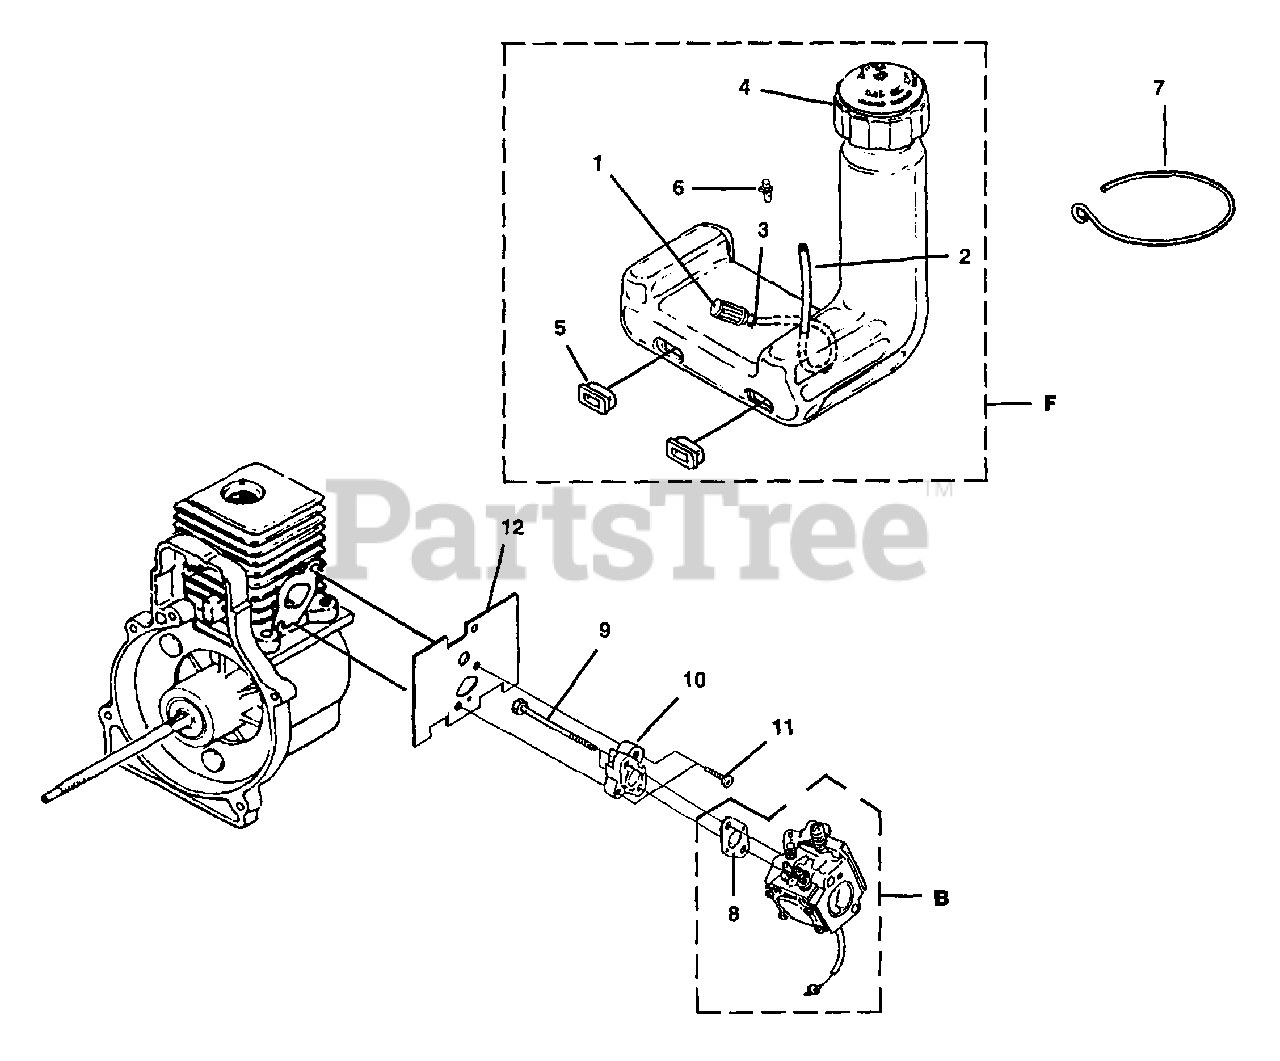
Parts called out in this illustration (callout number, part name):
1	FILTER-Fuel
2	TUBING-Rubber (5")
3	CLAMP-Wire
4	FUEL CAP
5	BUMPER-Rubber
6	FITTING-In Line Fuel
7	SUPPORT WIRE
8	GASKET-Carburetor
9	SCREW-Shoulder (10-24 x 2.8")
10	HEAT DAM
11	SCREW-Taptite (10-24 X 1")
12	GASKET-Heat Dam
F	FUEL TANK COMPLETE
B	CARBURETOR KIT
